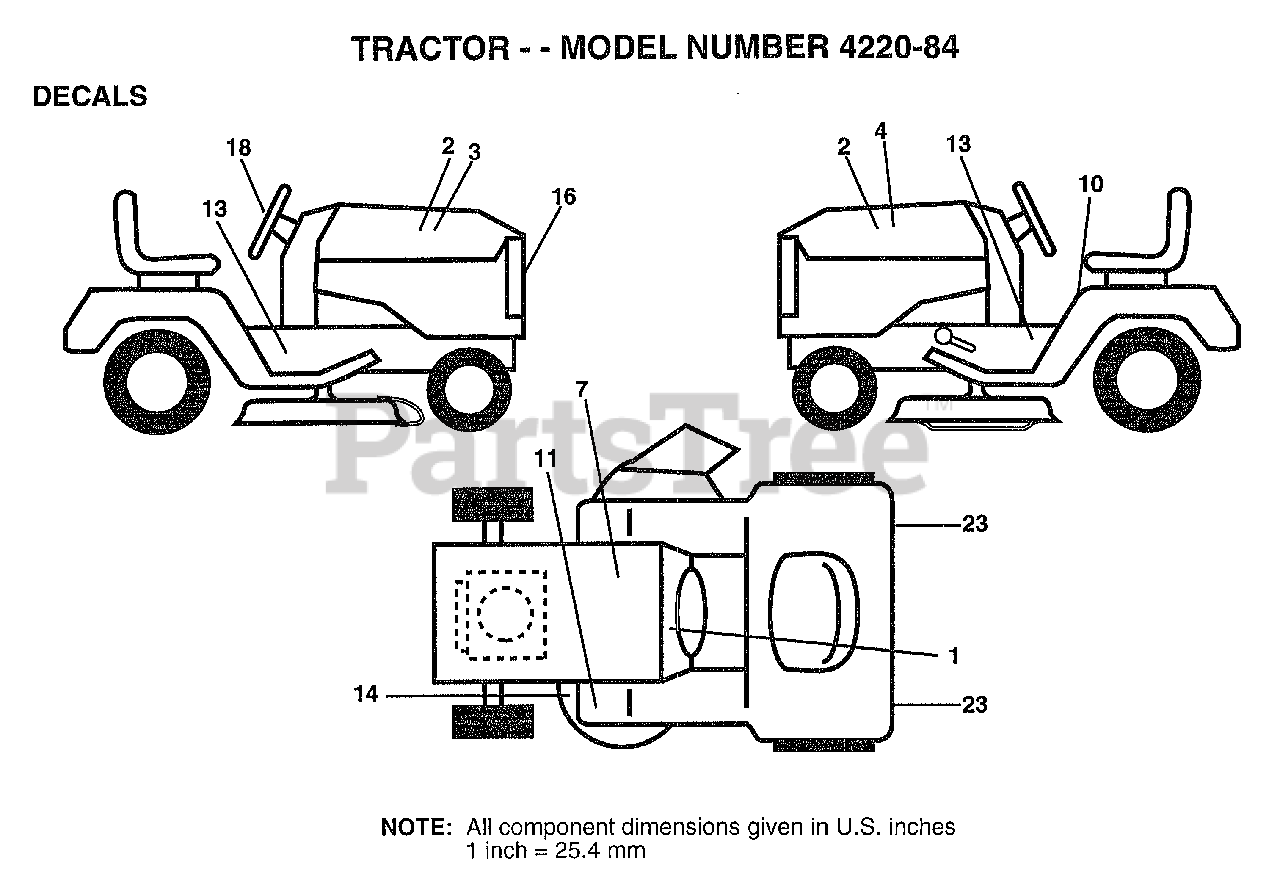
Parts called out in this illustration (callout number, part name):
1	"DECAL-OPER,GEAR D"
2	NAMEPLATE LOGO
4	HOOD DECAL LH
7	DECAL.BATRY.3-3908
10	"DECAL DANGER,FEND"
13	DECAL CHASSIS
16	GRILL DECAL
23	REFLECTOR-TAIL YT
